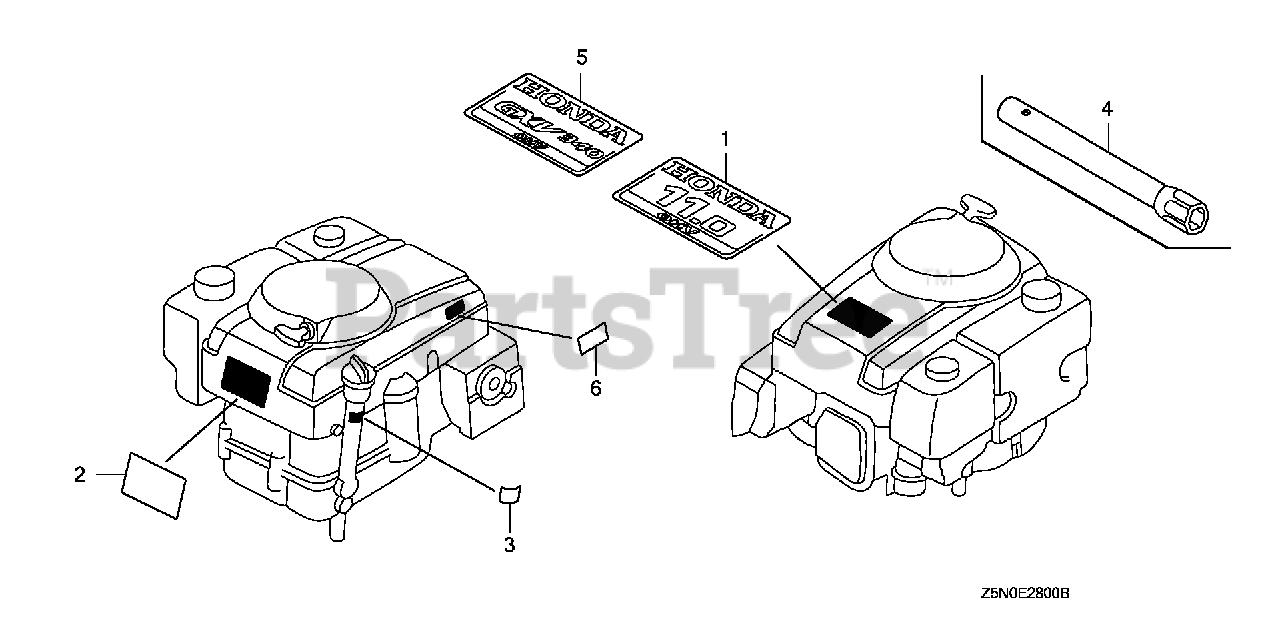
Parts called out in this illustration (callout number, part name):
1	EMBLEM, TOP COVER (11.0)
2	MARK, OPERATOR CAUTION (ENGLISH)(MADE IN THAI)
2	MARK, OPERATOR CAUTION (PICTOGRAPH)(MADE IN THAI)
3	MARK, TYPE (DX3)
4	WRENCH, BOX (P21)
5	EMBLEM, TOP COVER (GXV340)
6	MARK, EX. CAUTION (ENGLISH)
